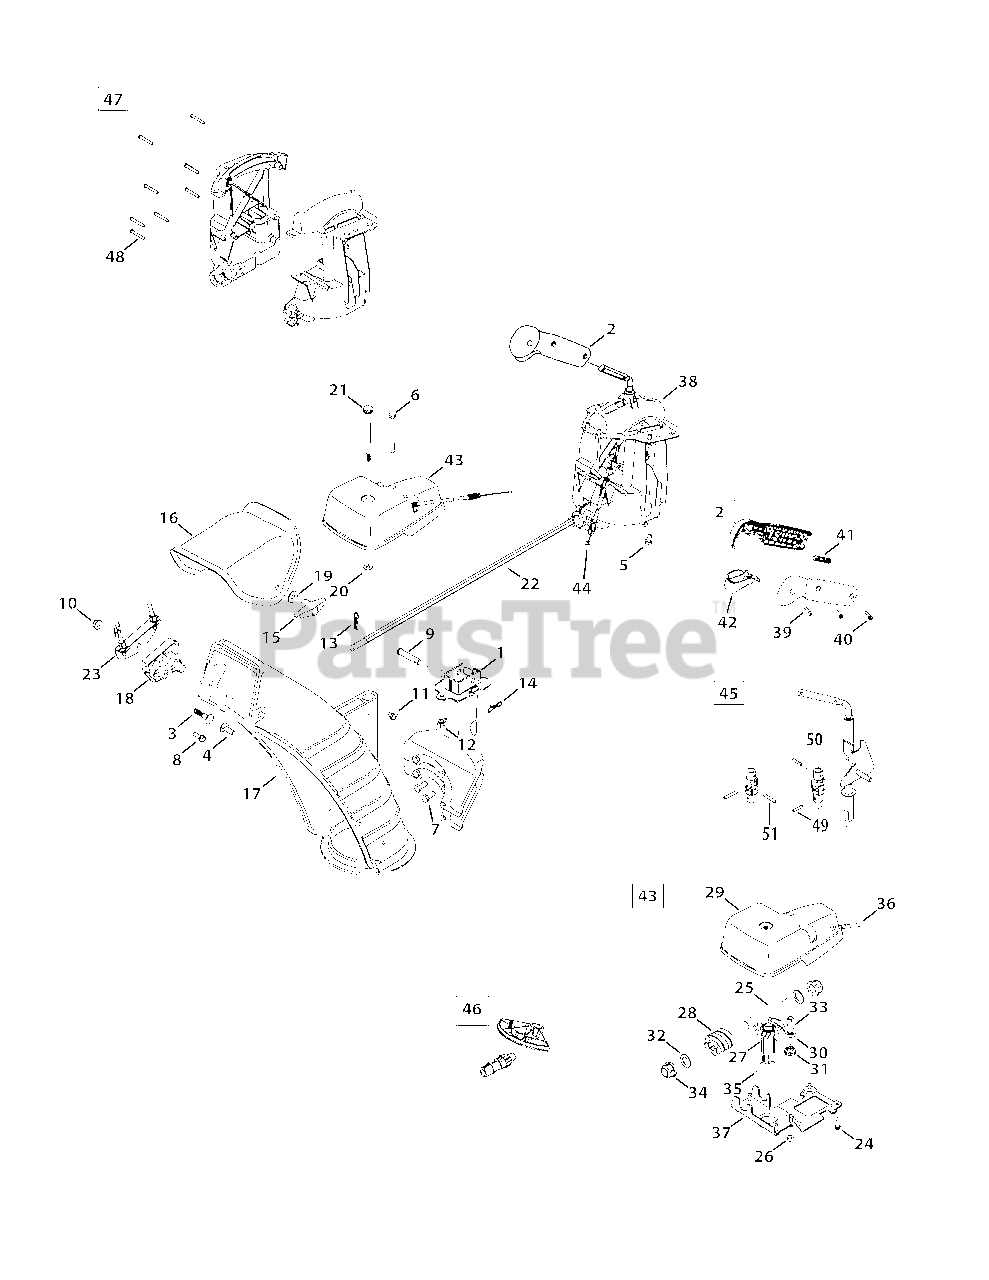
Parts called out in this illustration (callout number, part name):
1	Chute Support Bracket (large. block)
1	Chute Support Bracket (small block)
2	Trigger Handle Housing Assembly Kit
3	Bolt, Carriage, 5/16-18 x 1.50, 4-Way
3	Bolt, Carriage, 5/16-18 x .750, 2-Way
4	Bolt, Carrier, 5/16-18 x 1.00
5	Screw, Hi-Lo, 1/4-15 x 0.50
6	Hex Head Screw, 1/4-20 x 3.00
7	Hex Head Screw, 5/16-24 x .750
8	Screw, Hi-Lo, 1/4-15 x 0.750
9	Clevis Pin, 3/8 x 1.87
10	Nut, Flange Lock, 5/16-18
11	Nut, Flange Lock, 1/4-20
12	Wing Nut, 1/4-20
13	Internal Cotter Pin
14	Bow-Tie Cotter Pin
15	Wing Knob, 5/16-18
16	Chute, Upper, 4-Way
16	Chute, Upper, 2-Way
17	Chute, Lower
18	Cable Guide, Chute Tilt
19	Washer, Flat, .349 x .879
20	Washer, Flat, .25 x .630
21	Screw, Shoulder, .312 x 3.5 x 1/4-20
22	Chute Rod, 3/8 Hex
23	Cable Bracket
24	Screw, 12-16 x .75
26	Hexlock Nut, 1/4-28
27	Gear, 14 T
28	Worm
29	Gear Cover
31	Torsion Spring, .721 ID x .474
32	Washer, Flat, .625 x 1.0 x .067
33	Screw, Shoulder, .34 x .95 x 1/4-28
34	Hex Bearing
35	Flange Bearing
37	Gear Bracket
38	Chute Control, 4-Way
38	Chute Control, 2-Way
39	Screw, #8 x 1.00
40	Screw, 8-32 x .750
41	Joystick Plug
42	Joystick Trigger
43	Chute Rotation Gearbox
44	4-Way Cable
44	4-Way Cable w/Clip
45	Shift Assembly
46	Gear Set Assembly Kit
47	Chute Control Housing Kit, 4-Way
47	Chute Control Housing Kit, 2-Way
48	Screw, #8-18 x 1.250
50	Block, Asm Joint
51	Pin, Roll
